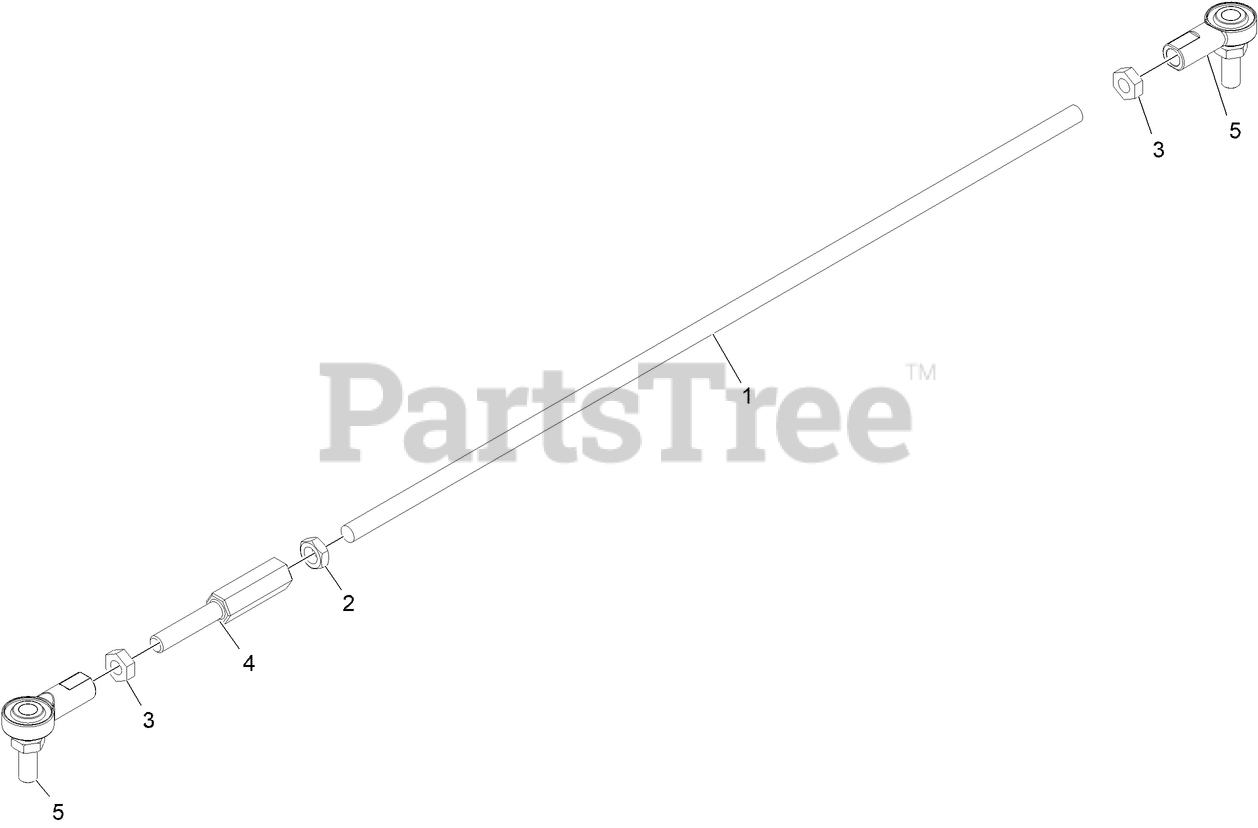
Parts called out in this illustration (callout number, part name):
1	ROD-MOTION CONTROL LONG
2	NUT-JAM
3	NUT-JAM
4	ROD-ADJUST
5	BALLJOINT
